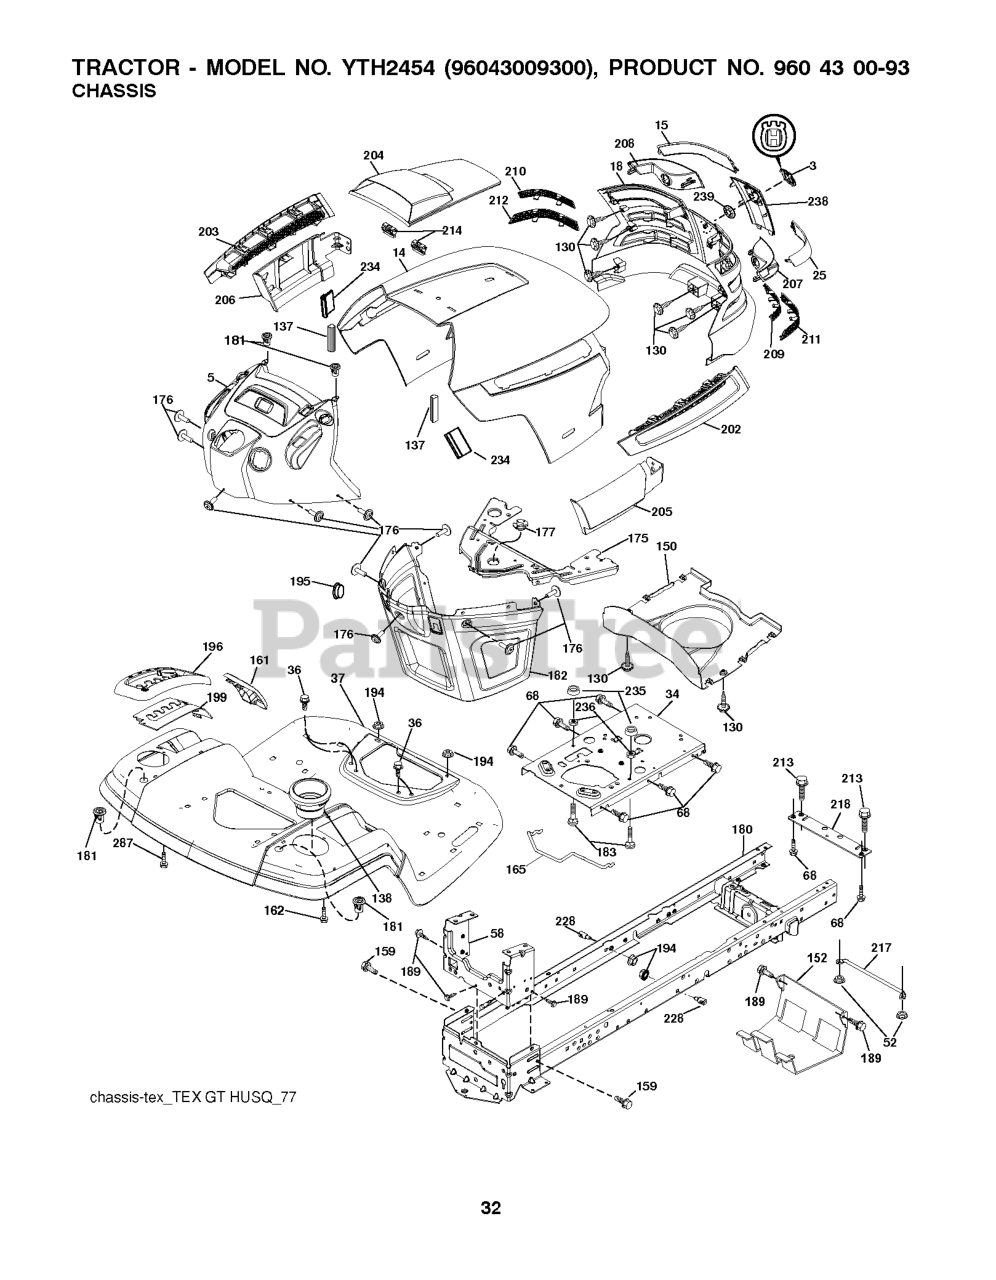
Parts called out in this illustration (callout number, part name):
3	RP LOGO
14	HOOD
15	LENS.LH.TEX.GT.HUSQ.CL
18	GRILL.ASM.HUSQ.TG/CRD.W/TRIM
25	LENS.RH.TEX.GT.HUSQ.CL
34	PLATE.ENGINE.WELDED.CHASSIS
36	SCREW 5/16"
37	FENDER.TLT.W/CPH.W/FW.ORANGE
52	LOCKNUT
58	DRAWBAR UPPER 2PC SMALL FENDER
68	Screw 5/16-18 x 1/2 Hex, Self Tapping 5/16-18 x 1/2
130	SCREW.#10 X 0.750.BOS
137	BUMPER DASH
138	CUPHOLDER.TL.TEX.418
150	AIR.DUCT.HOOD.TEX.GT.HUSQ
152	SHIELD.BROWNING.W/TEX
161	WINDOW FUEL
162	SCREW.HI-LO.CONSOLE
165	SUPPORT.TANK.REAR.W/TEX
175	PLATE.CROSSMEMBER.HUSQ
176	SCREW.#10-24X5/8.RN.QU
177	BUSHING, STEERING
180	CHASS.WLDMNT.TL.12GA/2P.48/54
181	BUSHING.MNT.FEND.CRGO.
182	DASH.LOWER.COMMON.12V.ADAPTOR
183	BOLT.5/16-18X1-1/4 FULL THD
189	SCREW
194	NUT LOCK HEX FLANGE 5/16-18
195	PLUG.HOLE.DASH.LOWER.12V.BLK
196	RP CONSOLE.ASM.DECKLFT.GR/RBT.
199	PLATE.DECK.LIFT.HUSQ.LT
202	VENT.SIDE.HOOD.HUSQ.RH.GREY
203	VENT.SIDE.HOOD.HUSQ.LH.GRAY
204	HOOD VENT
205	SKIRT.HOOD.SIDE.HUSQ.RH.GREY
206	SKIRT.HOOD.SIDE.HUSQ.LH.GREY
207	BEZEL.RH.TEX.GT.HUSQ
208	BEZEL.LH.TEX.GT.HUSQ
209	INSERT.HEX.GRILL.HUSQ.GREY
210	INSERT.HEX.GRILL.HUSQ.
211	INSERT.HEX.GRILL.HUSQ.
212	INSERT.HEX.GRILL.HUSQ.
213	BOLT
214	CLIP.RETAINER.TINNER.
217	ROD.PIVOT.HOOD
218	X-PIECE.HOOD.STOP.NON/
228	STUD.FASTNER.W/ANTI-ROTATE
233	BOLT.SHOULDER
234	BUMPER.HOOD.TEX.HUSQVARNA
235	SPACER FENDER
236	NUT.CENTERLOCK.5/16-
238	TRIM.HUSQ.TG/CRD.SERVICE
239	NUT PUSH M
287	SCREW 1/4X20
